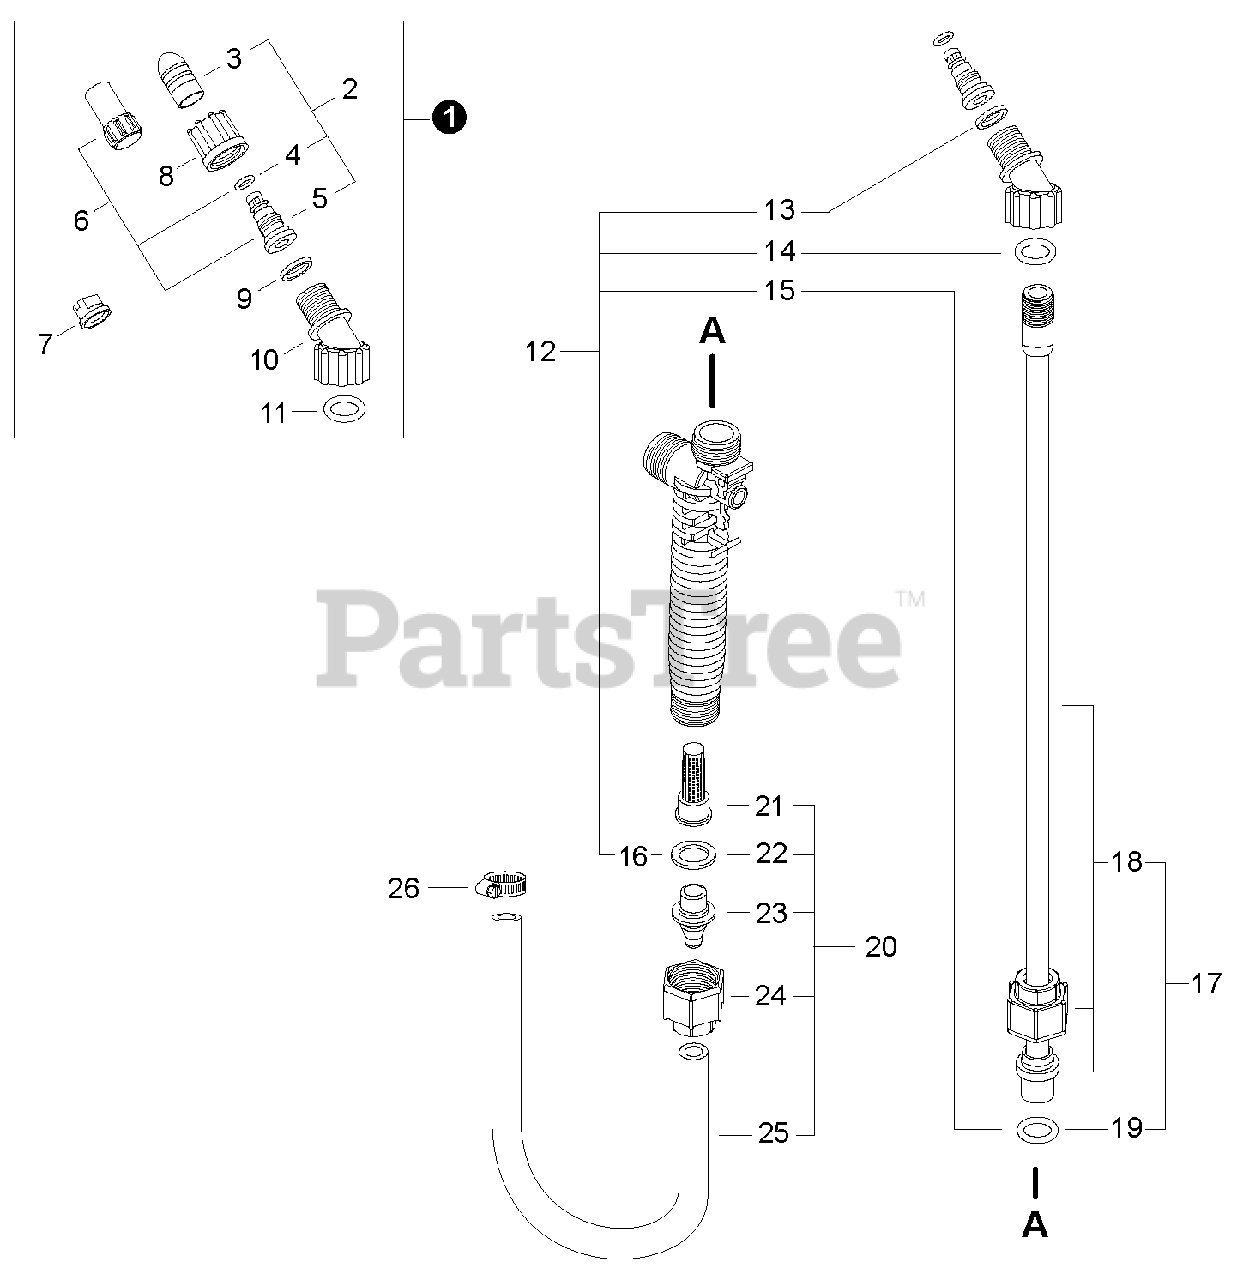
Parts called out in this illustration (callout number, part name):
1	NOZZLE KIT
2	NOZZLE KIT, BRASS
3	CAP, NOZZLE - BRASS
4	O-RING, NOZZLE
5	BODY, NOZZLE
6	NOZZLE KIT, PLASTIC
7	NOZZLE, FLAT FAN
8	NUT, NOZZLE
9	GASKET, NOZZLE
10	ELBOW, NOZZLE
11	O-RING, ELBOW
12	GASKET KIT, WAND
13	GASKET, NOZZLE
14	O-RING, ELBOW
16	GASKET, ADAPTER
17	WAND ASSY, PLASTIC
18	WAND, SPRAYER
20	HOSE KIT
21	FILTER, SPRAY GUN
22	GASKET, ADAPTER
23	ADAPTER, HOSE - BLACK
24	NUT, HOSE
26	CLAMP, HOSE
